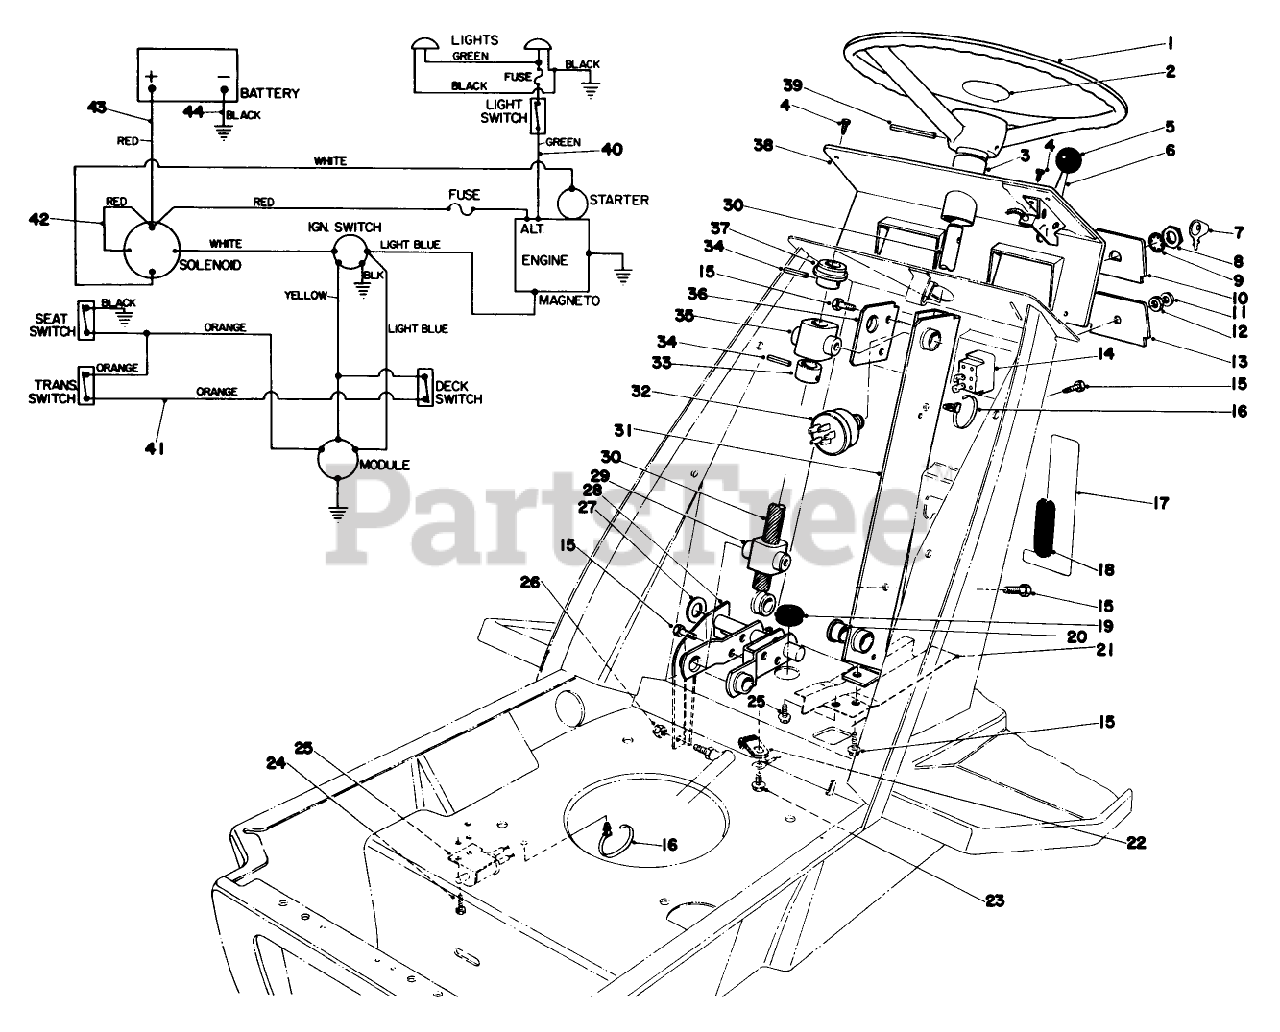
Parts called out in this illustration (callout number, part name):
4	Screw
5	KNOB-CONTROL
8	NUT-HH
9	WASHER-LOCK
12	NUT-LOCK
14	SWITCH-LIGHT
15	SCREW-THD ROLL, HWH
16	TIE-MOUNT, PUSH
19	GROMMET
20	BEARING-FLANGE
22	CLIP-FUEL LINE
23	SCREW-HWH
24	SCREW-TAPTITE
32	SWITCH-STARTER
33	STRG SHAFT COLLAR
34	PIN-SPRING
39	PIN-ROLL
43	WIRE ASM
44	WIRE ASM
